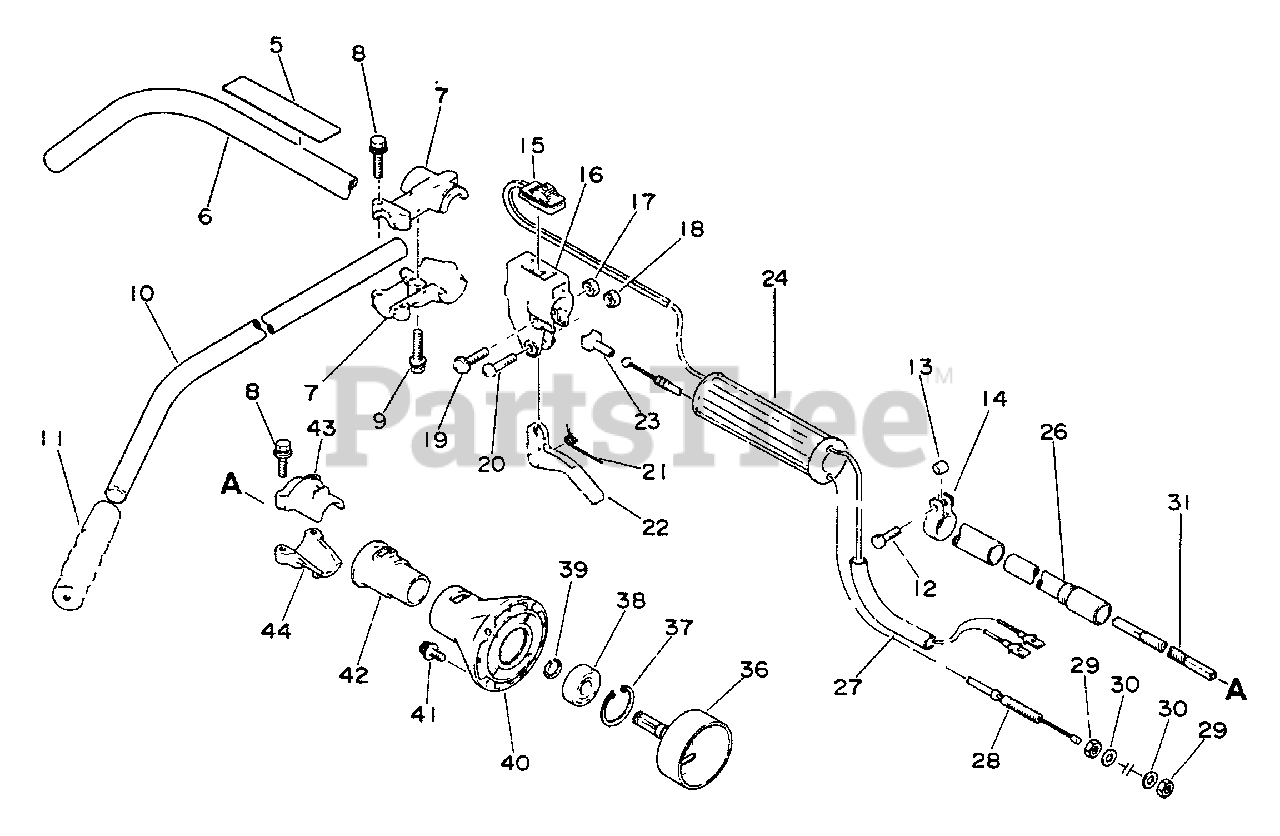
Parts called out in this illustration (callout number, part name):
5	LABEL
6	PIPE, MAIN
7	BRACKET, HANDLE
8	BOLT - 5×25
9	BOLT 5×28
10	HANDLE
12	BOLT 5×18
13	SPACER, GUARD
14	CLAMP
15	IGNITION SWITCH ASSY
16	BRACKET, THROTTLE
17	NUT M5
18	LOCKNUT - 5
19	SCREW 5×28
21	SPRING, THROTTLE
22	TRIGGER, THROTTLE
23	GUIDE, CABLE
24	GRIP, HANDLE
26	LINER
27	TUBE - VINYL
28	CABLE, THROTTLE
30	WASHER 6.5×11.5×0.8
31	DRIVESHAFT - FLEXIBLE
36	DRUM, CLUTCH
37	RING, SNAP Ø32
38	BEARING, BALL 6201
39	RING, SNAP Ø12
40	FLANGE, DRIVESHAFT
41	SCREW 5×16
42	CUSHION
43	HOLDER, MAIN PIPE
44	HOLDER, HOUSING
